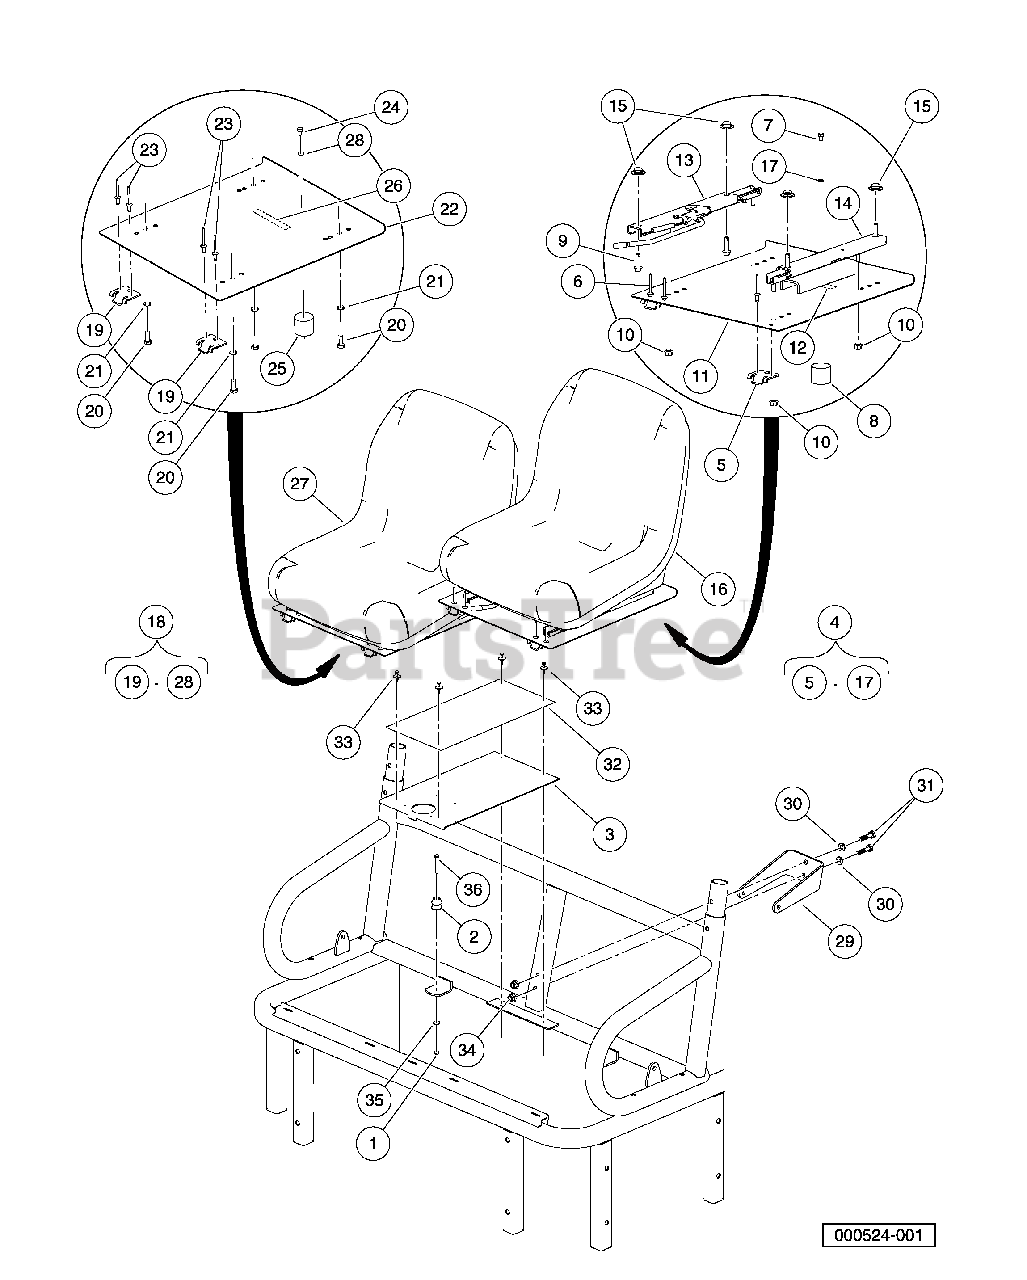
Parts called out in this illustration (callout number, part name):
1	Locknut, M6-1.00 Nylon Insert
2	Seat Holder Base
3	Pan, Center, Closeout
4	Asm, Bucket Seat Adjustable
5	Hinge Plate
6	Rivet, 1/4 X .438 Blind
7	Screw, 6m-1.00 X 10mm Hex Head.
8	Seat Holder Cup
9	Bolt, Flange Head, M8 X 30.0
10	Nut,m8,all Metal Lock
11	Pan, Seat, Driver Asm
12	Decal, Hot Surface Warning
13	Adjuster, Forward/Aft
14	Adjuster, Slider
15	Washer, Bell
16	Seat, Bucket, Gray
17	Lockwasher, 1/4 Helical Split
18	Assembly, Bucket Seat w/Spacers
19	Hinge Plate
20	Screw, M8-125 X 22 Hex-Head
21	Lockwasher, 8mm Split
22	Pan, Seat, Passenger
23	Rivet, 1/4 X .438 Blind
24	Screw, 6m-1.00 X 10mm Hex Head
25	Seat Holder Cup
26	Decal, Hot Surface Warning
27	Seat, Bucket, Gray
28	Lockwasher, 1/4 Helical Split
29	Bracket, Seatbelt, Bolt-On
30	Washer, Hard, M10, Zn-Ni/Blk
31	Bolt, M10 X 45, Zn-Ni (Black)
32	Cover, Center Console
33	Rivet, Removable, Tuflok 1/4"
34	Nut, Flanged, M10 x 1.5, Black
35	Washer, 1/4 Type A Narrow Flat
36	Bolt, M6 X 1 X 45
